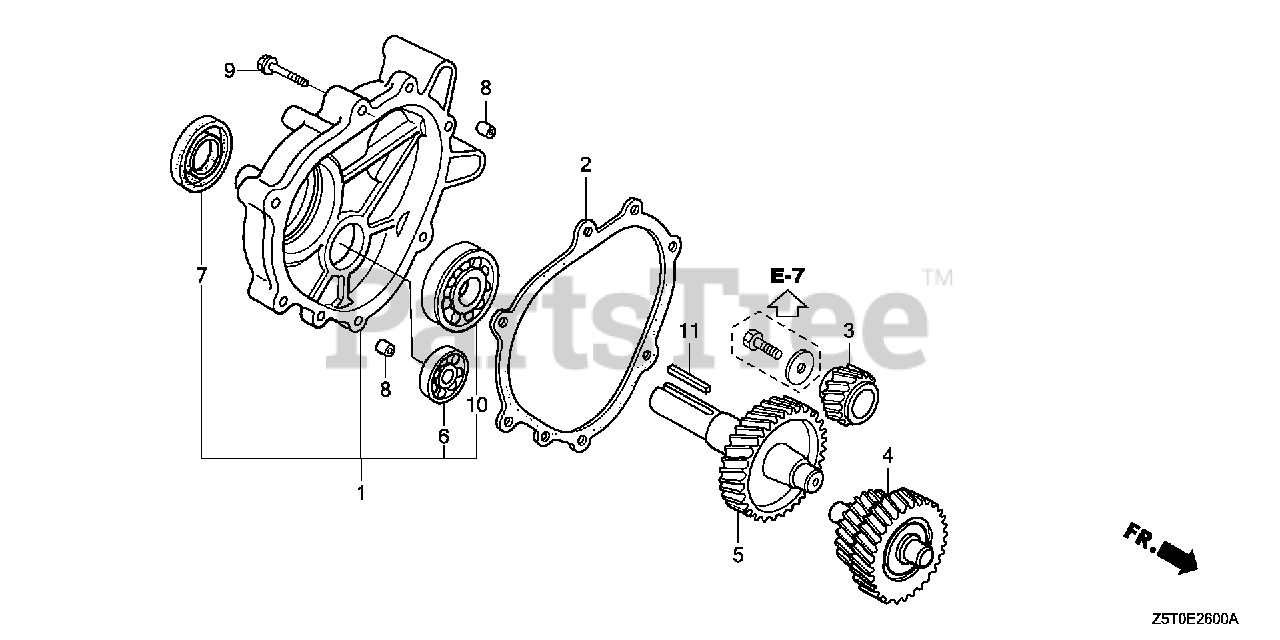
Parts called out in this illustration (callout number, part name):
1	COVER ASSY., GEAR CASE
2	GASKET, CHAIN CASE COVER
3	GEAR, PRIMARY DRIVE (12T)
4	COUNTERSHAFT (13T/27T)
5	SHAFT, P.T.O. (H-TYPE)
6	BEARING, RADIAL BALL (6302)
7	OIL SEAL (30X46X8) (NOK ASIA)
8	PIN A, DOWEL (8X14)
9	BOLT, FLANGE (8X40) Use up to Engine SN 1003236.
10	BEARING, RADIAL BALL (6206) (NTN CORP.)
11	KEY (6.3X6.3X43)
